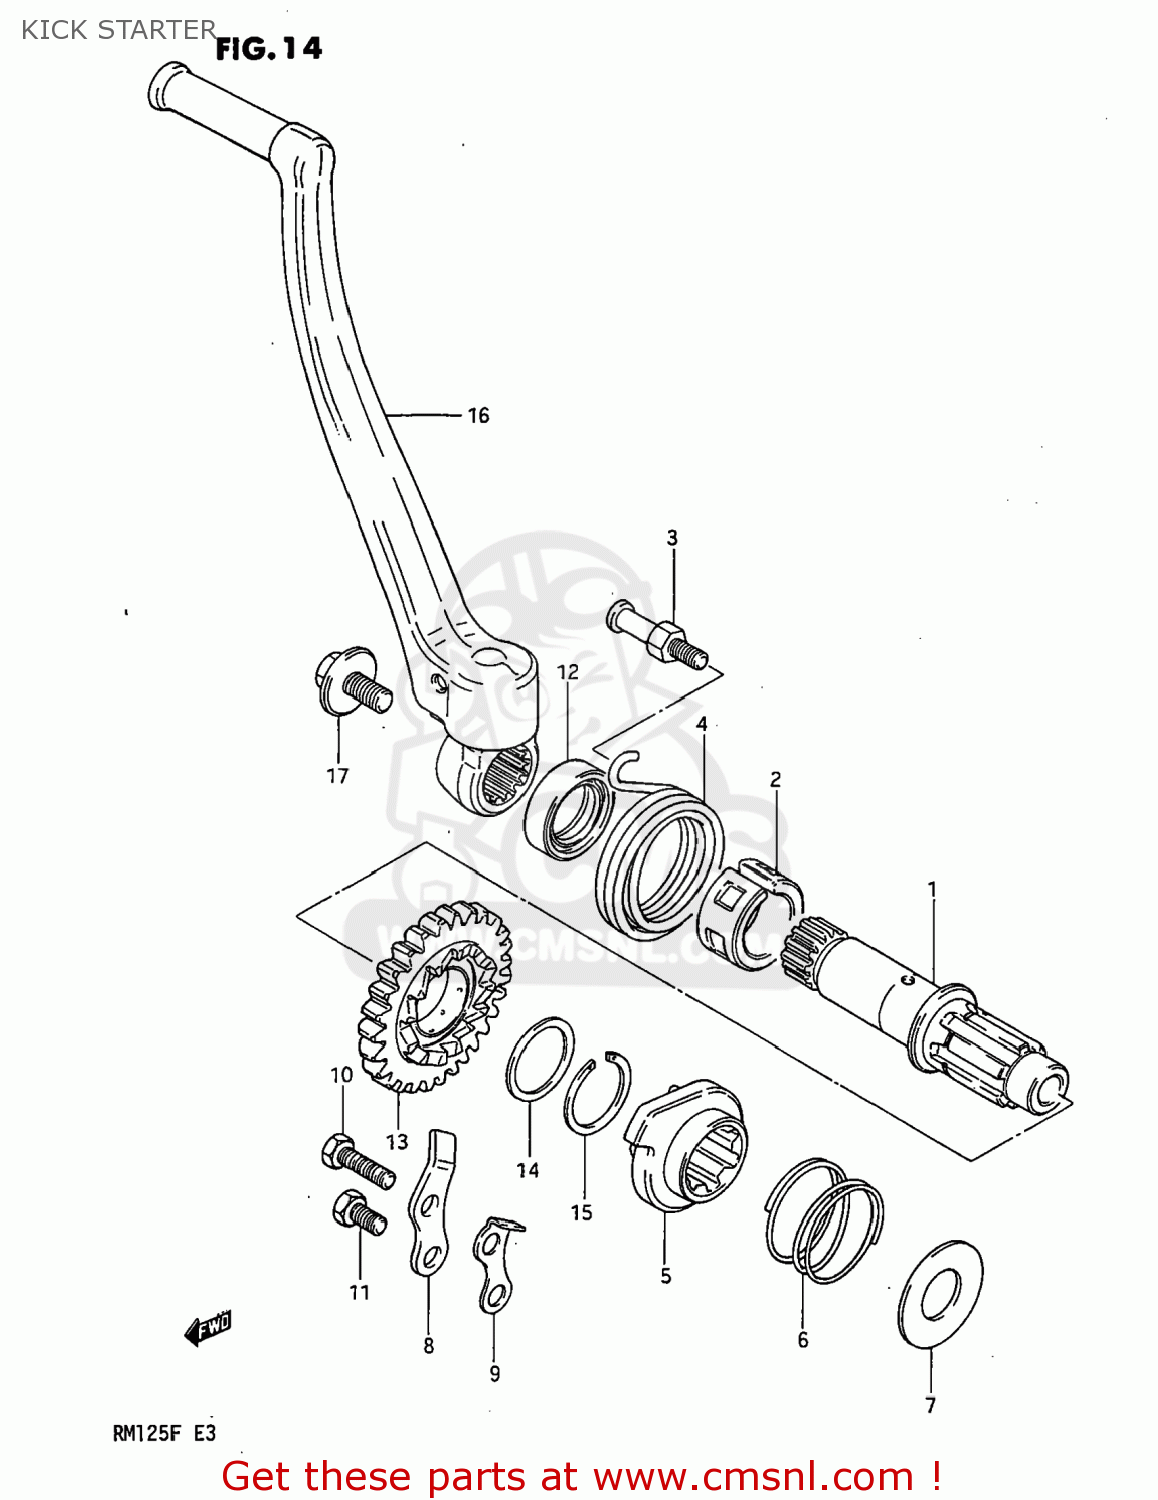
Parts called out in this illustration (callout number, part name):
1	SHAFT,KICK STARTER
2	GUIDE,KICK SHAFT SPRING
3	BOLT,KICK SHAFT SPRING
4	SPRING
5	STARTER,KICK
6	SPRING
7	WASHER
8	GUIDE,KICK STARTER
9	STOPPER,KICK STARTER
10	BOLT, UPPER
11	BOLT
12	SEAL,OIL(20X27X5)
13	GEAR,KICK STARTER DRIVE
14	SHIM
15	CIRCLIP
16	LEVER ASSEMBLY,KICK STARTER
17	BOLT(8X14)
